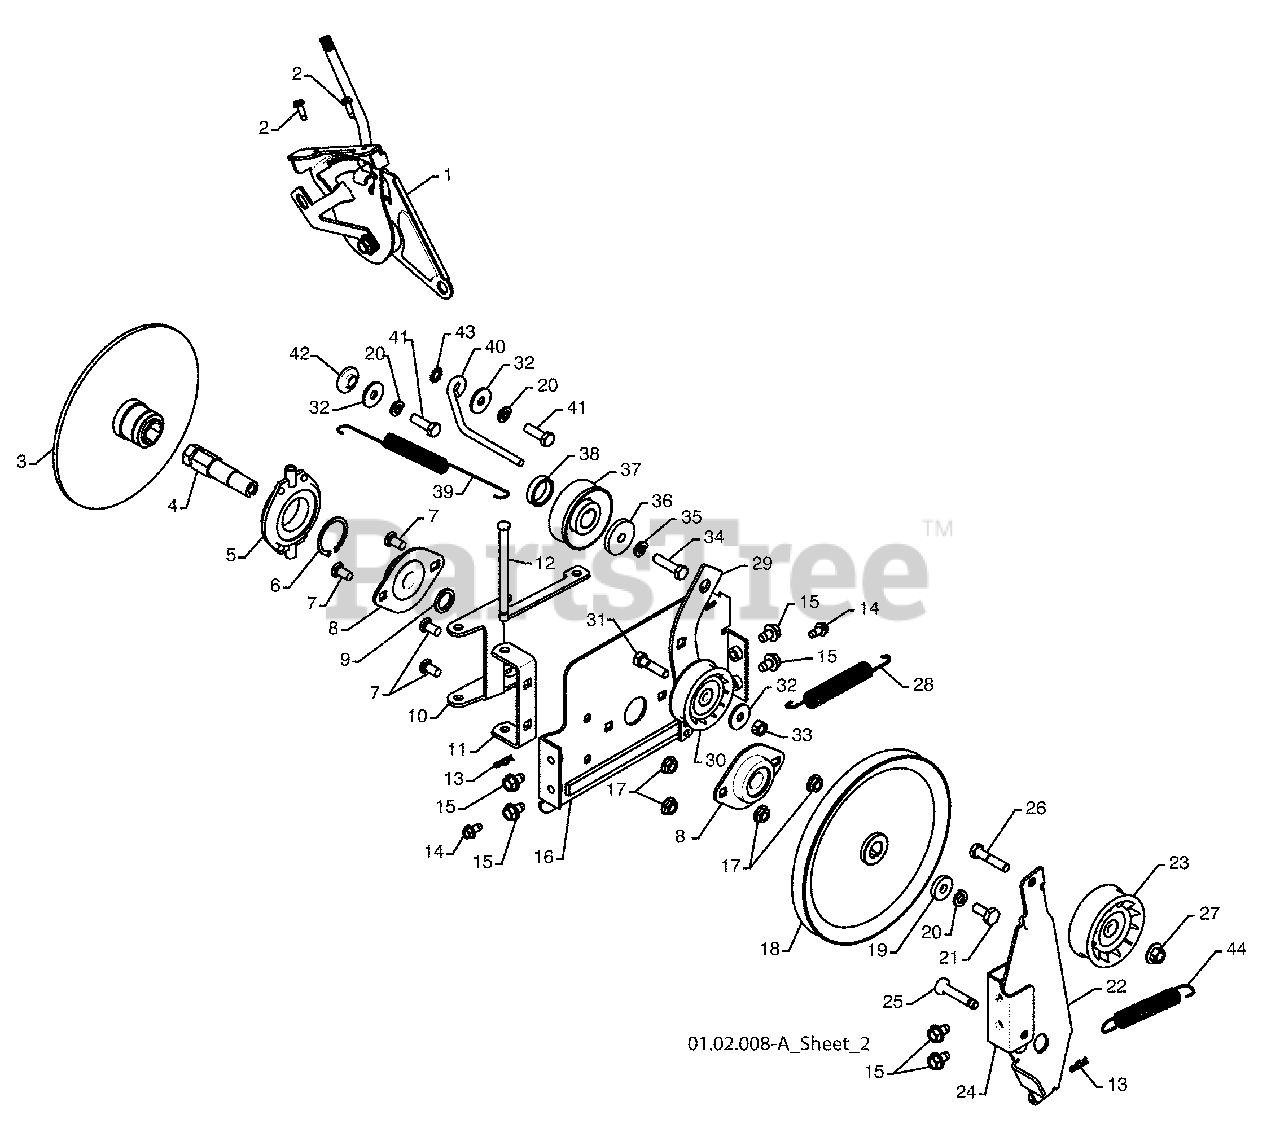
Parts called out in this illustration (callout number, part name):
1	SPEED SELECTOR HEAD ASSEMBLY
2	SCREW 10--24 X .625
3	DRIVE PLATE WELDMENT
5	TRUNNION BEARING ASSEMBLY
6	RETAINER
7	CARRIAGE BOLT 5/16--18 X .625
8	FLANGE BEARING
10	LEVER SHIFTER PLATE
11	SHIFTER SUPPORT BRACKET
14	SCREW 1/4--20 X .500
15	BOLT 5/16--18 X .500
16	DRIVE MOUNT PLATE
17	NUT 5/16--18
18	TRACTION PULLEY
20	LOCKWASHER 5/16
21	SCREW 5/16--18 X .750
22	IDLER BRAKE ARM
23	IDLER PULLEY
24	IDLER PIVOT BRACKET
26	SCREW 5/16--18 X 1.50
27	NUT 5/16--18
28	TRACTION SPRING
29	IDLER TRACTION ARM
30	IDLER PULLEY
31	SCREW 5/16--18 X 1.25
33	NUT 5/16--18
34	SCREW 5/16--24 x 1 1/4
35	LOCKWASHER 5/16
37	ENGINE TRACTION PULLEY
39	RETURN SPRING
40	BELT GUIDE
41	SCREW 5/16--18 X 1.00
42	BUSHING
43	LOCKWASHER 5/16
44	BRAKE SPRING
